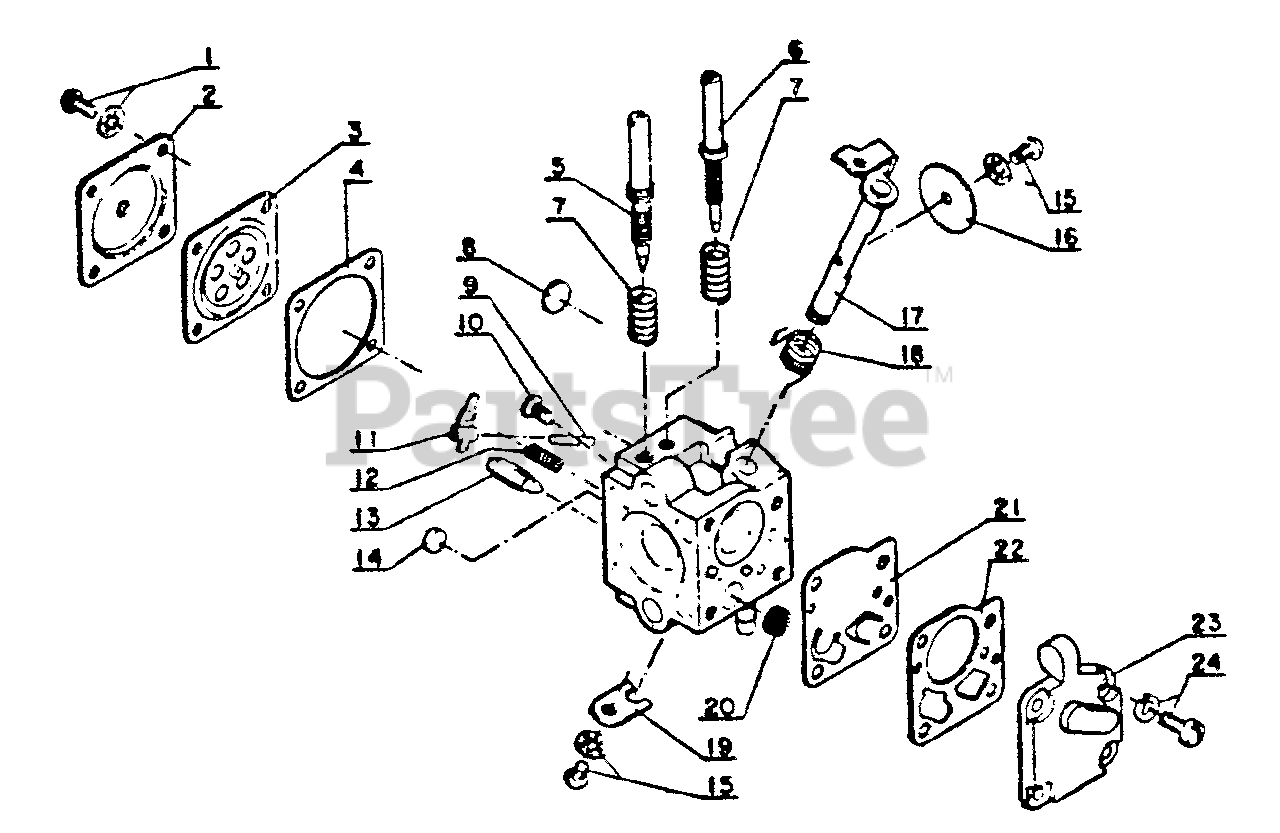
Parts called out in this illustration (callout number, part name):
1	SCREW
2	COVER, DIAPHRAGM
3	DIAPHRAGM
4	GASKET, DIAPHRAGM
5	SCREW, MAIN ADJUST
6	SCREW, IDLE ADJUST
7	SCREW, IDLE ADJUST
8	PLUG, WELCH - LARGE
9	PIN, METERING LEVER
10	SCREW, METERING LEVER PIN
11	LEVER, METERING
12	SPRING, METERING LEVER
13	VALVE, NEEDLE
14	PLUG, WELCH - SMALL
15	SCREW
16	VALVE, THROTTLE
17	SHAFT, THROTTLE
18	SPRING, RETURN
19	CLIP, THROTTLE SHAFT
20	FILTER, FUEL
21	DIAPHRAGM, PUMP
22	GASKET, PUMP
23	COVER, PUMP
24	SCREW
